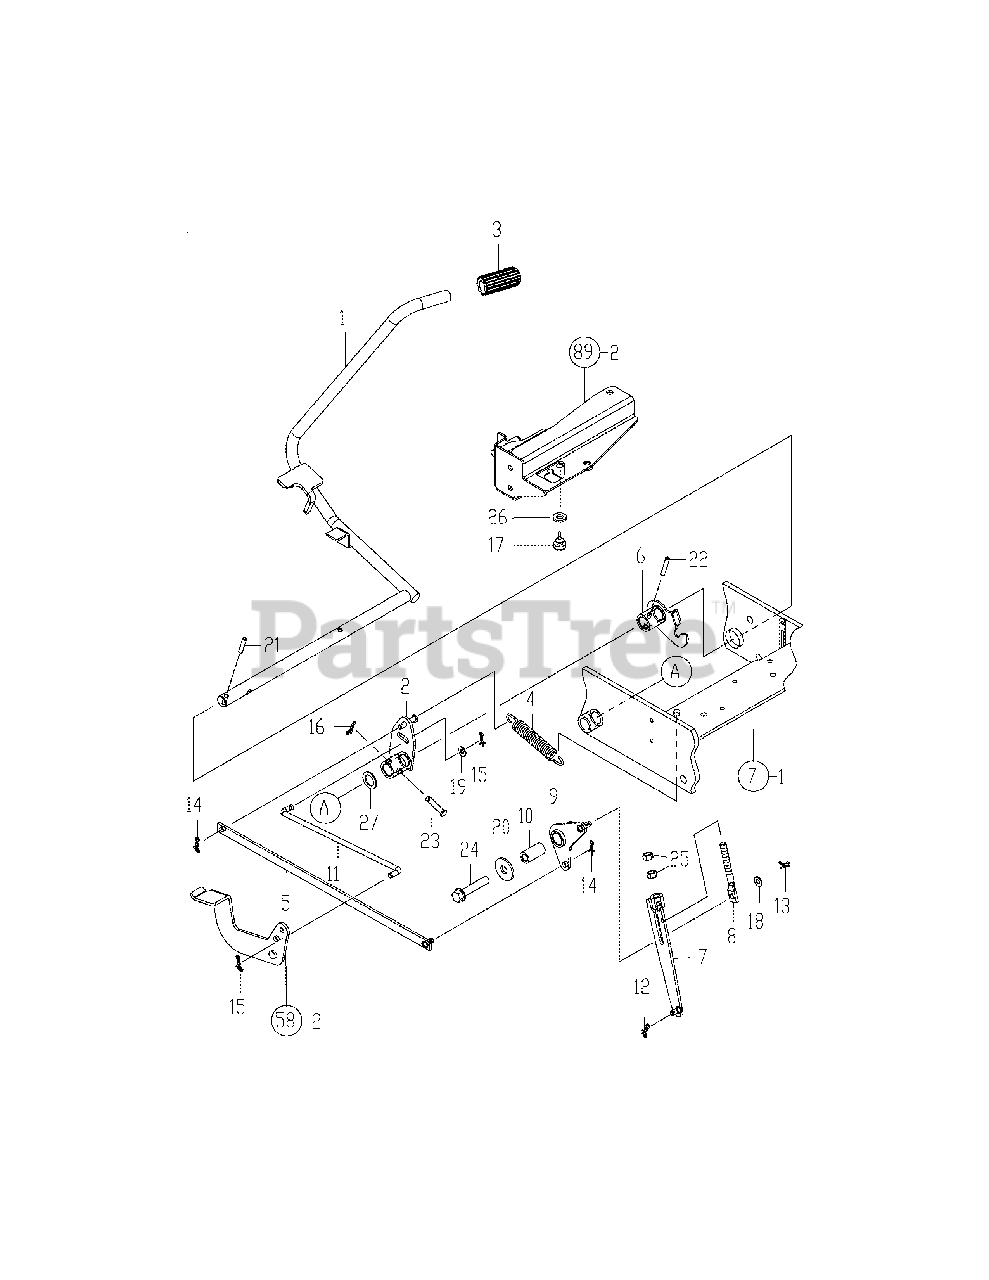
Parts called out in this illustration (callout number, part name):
1	Pedal Cmp, Brake
2	Arm Cmp, Brake
3	Head,Brake Pedal
4	Spring, Return
5	Rod Cmp, Brake
6	Arm,Release Cmp
9	Arm Cmp,Brake Rear
21	Pin, 6.0A X 32
22	Pin, 6.0A X 40
26	Washer, 10
27	Washer 20X30X2
